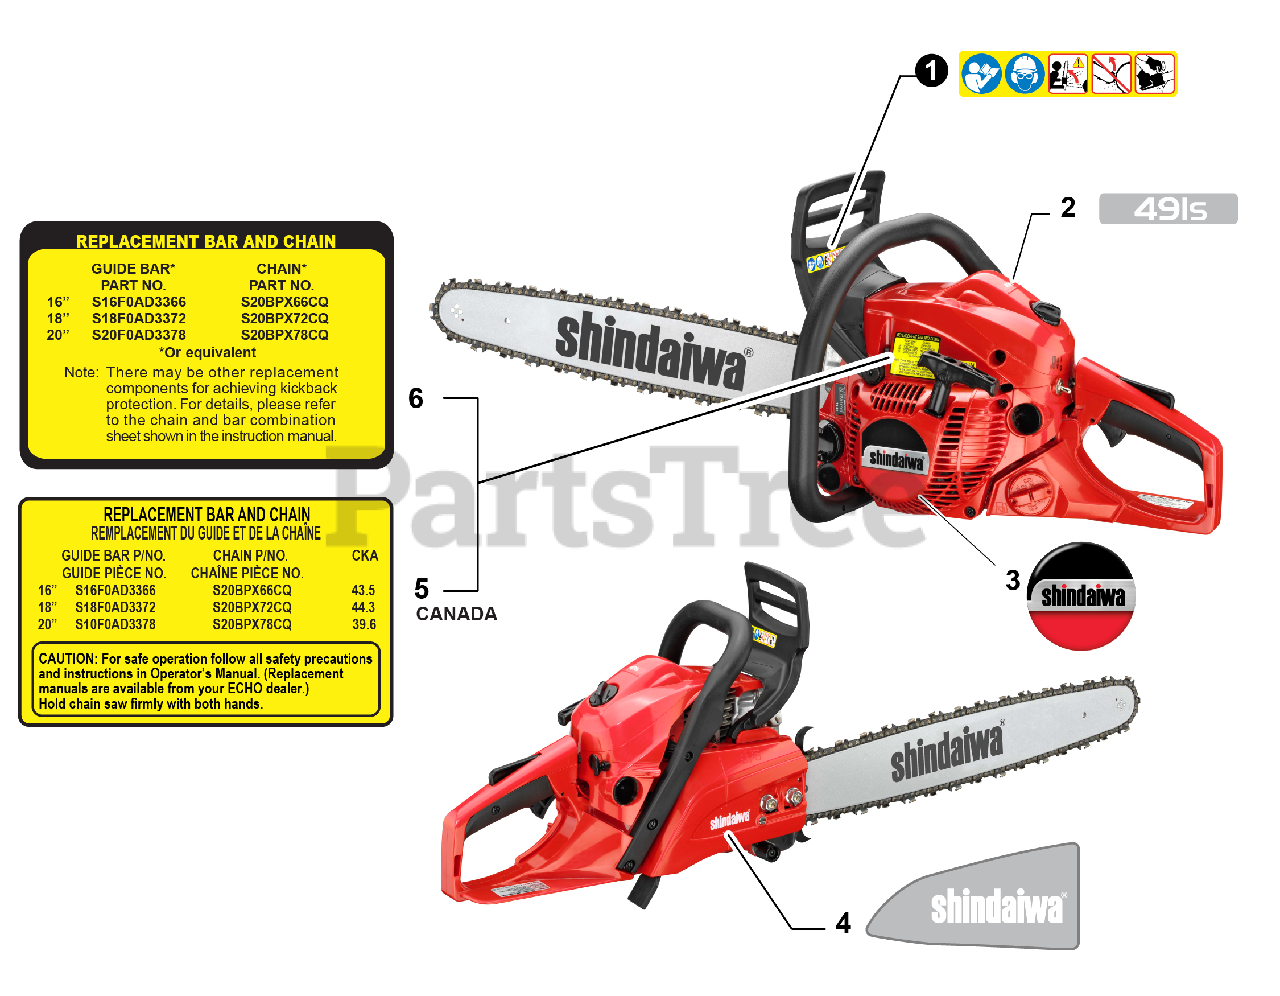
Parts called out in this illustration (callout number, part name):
1	LABEL, CAUTION
2	LABEL - MODEL 491s
3	LABEL, STARTER - shindaiwa
4	LABEL - shindaiwa
5	LABEL, BAR & CHAIN
6	LABEL, BAR & CHAIN
